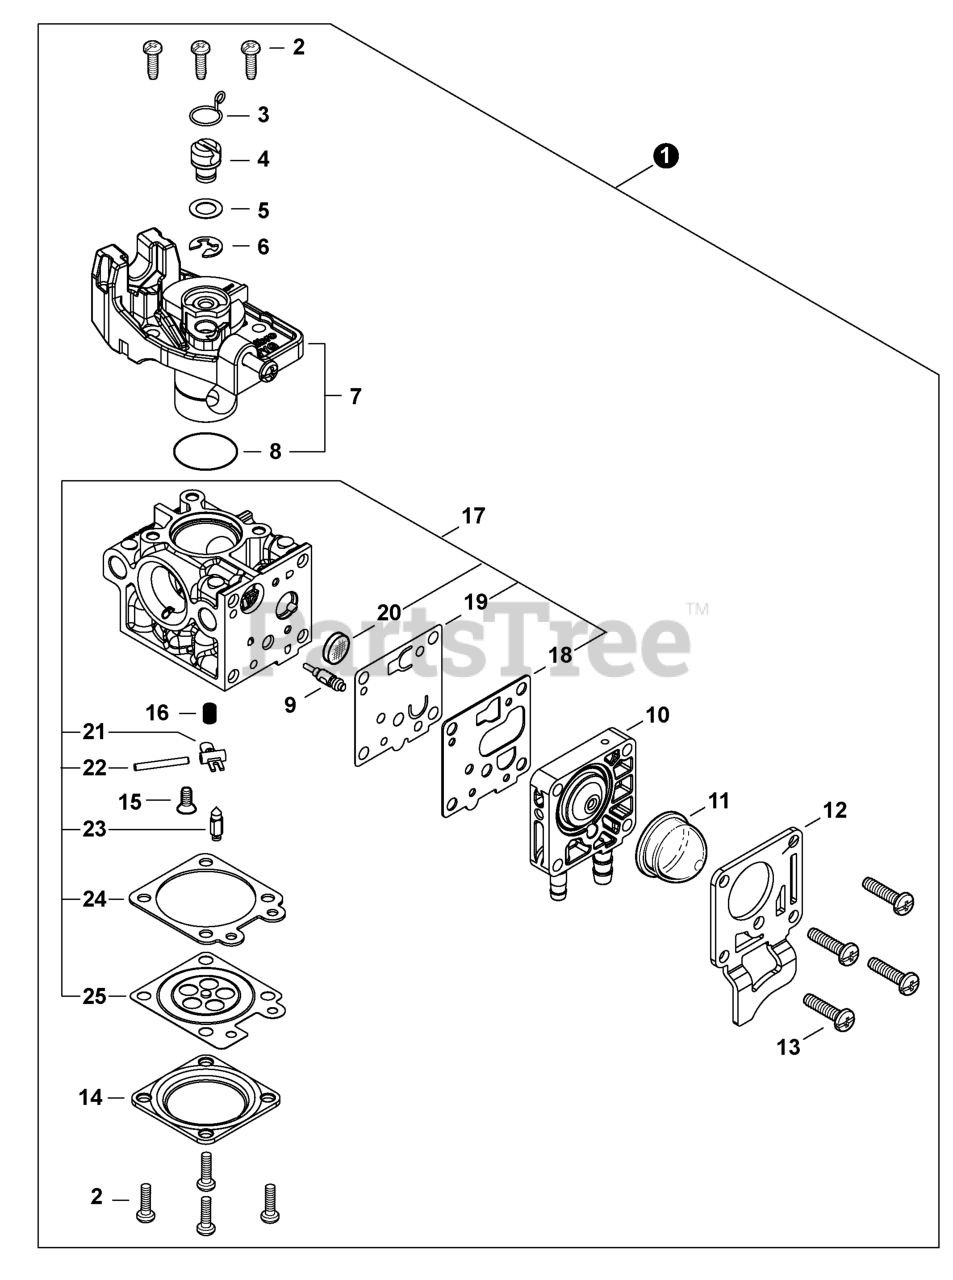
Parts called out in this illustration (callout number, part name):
1	CARBURETOR - WYG-23A
7	THROTTLE VALVE ASSY
9	NEEDLE, MIXTURE
10	BODY ASSY, PUMP
11	BULB, PURGE
12	COVER, FUEL PUMP
14	COVER, METERING DIAPHRAGM
17	REPAIR KIT, CARBURETOR
18	GASKET, FUEL PUMP
19	DIAPHRAGM, FUEL PUMP
20	SCREEN, FUEL INLET
21	LEVER, METERING
22	PIN, METERING LEVER
23	VALVE, INLET NEEDLE
24	GASKET, METERING DIAPHRAGM
25	DIAPHRAGM, METERING
